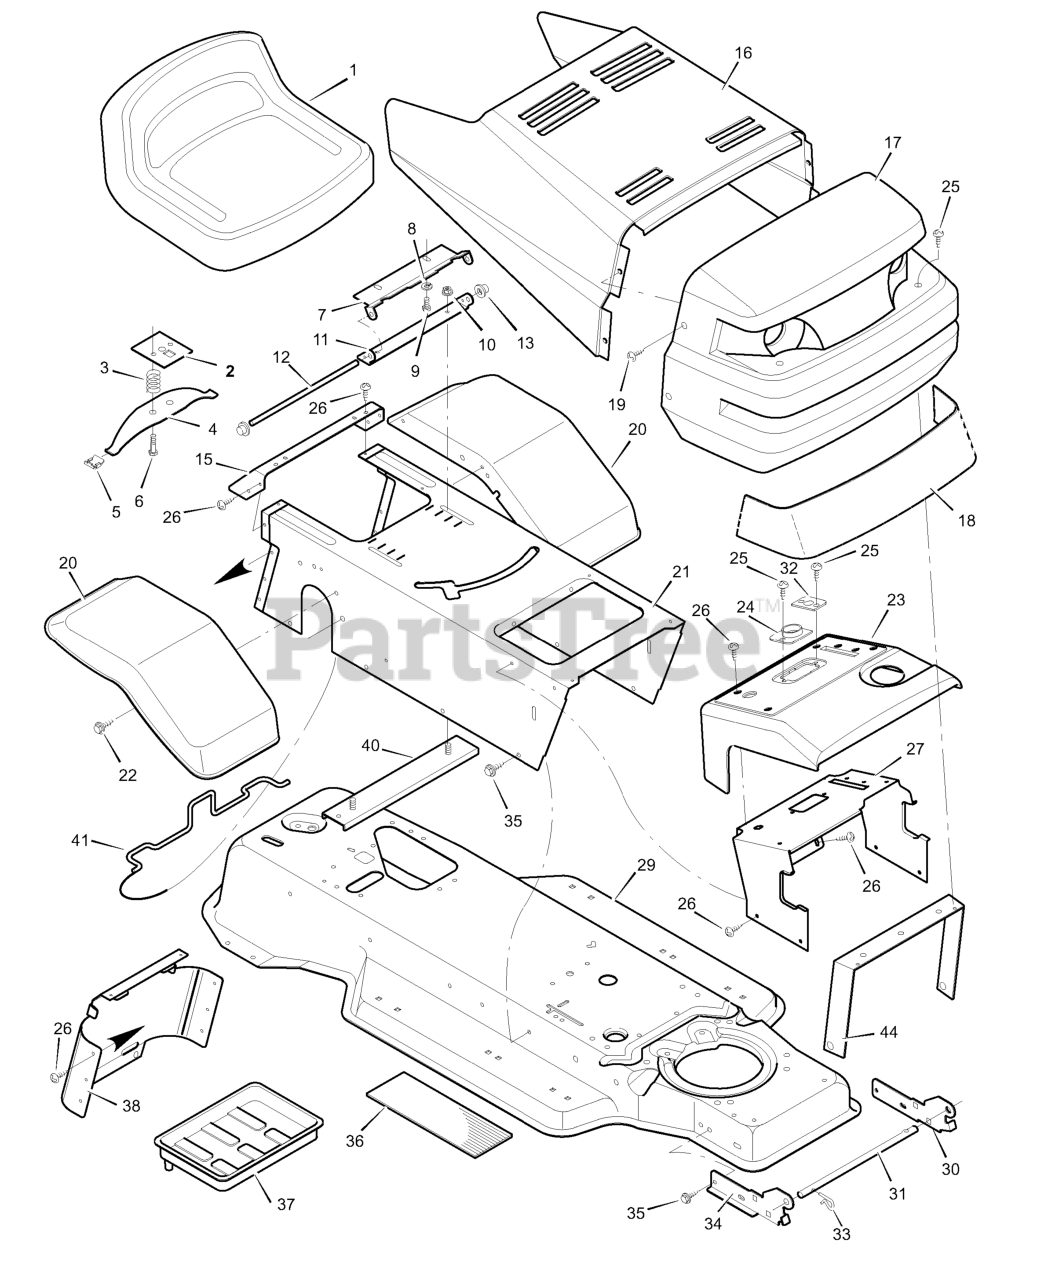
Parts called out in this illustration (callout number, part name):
2	Plate Assembly, Switch
3	Spring, Compression
4	Spring, Seat
5	Glide, Spring
6	Bolt, Shoulder
7	Support, Seat
8	Lockwasher
9	Bolt, Hex
10	Locknut, Flange
11	Bracket, Pivot
12	Rod, Pivot
13	Cap, Push On
15	Fender, Apron
17	Grille Assembly
21	Console Assembly
23	Dash Panel
24	Bearing, Steering
26	Screw
27	Support, Dash
29	Frame Assembly
30	Bracket, Left Grille
31	Rod, Pivot
32	Bearing
33	Pin, Hair
34	Bracket, Right Grille
37	Tray, Battery
38	Cap, Console
39	Bolt
40	Channel Assembly
41	Clamp, Battery
44	Brace, Grille
